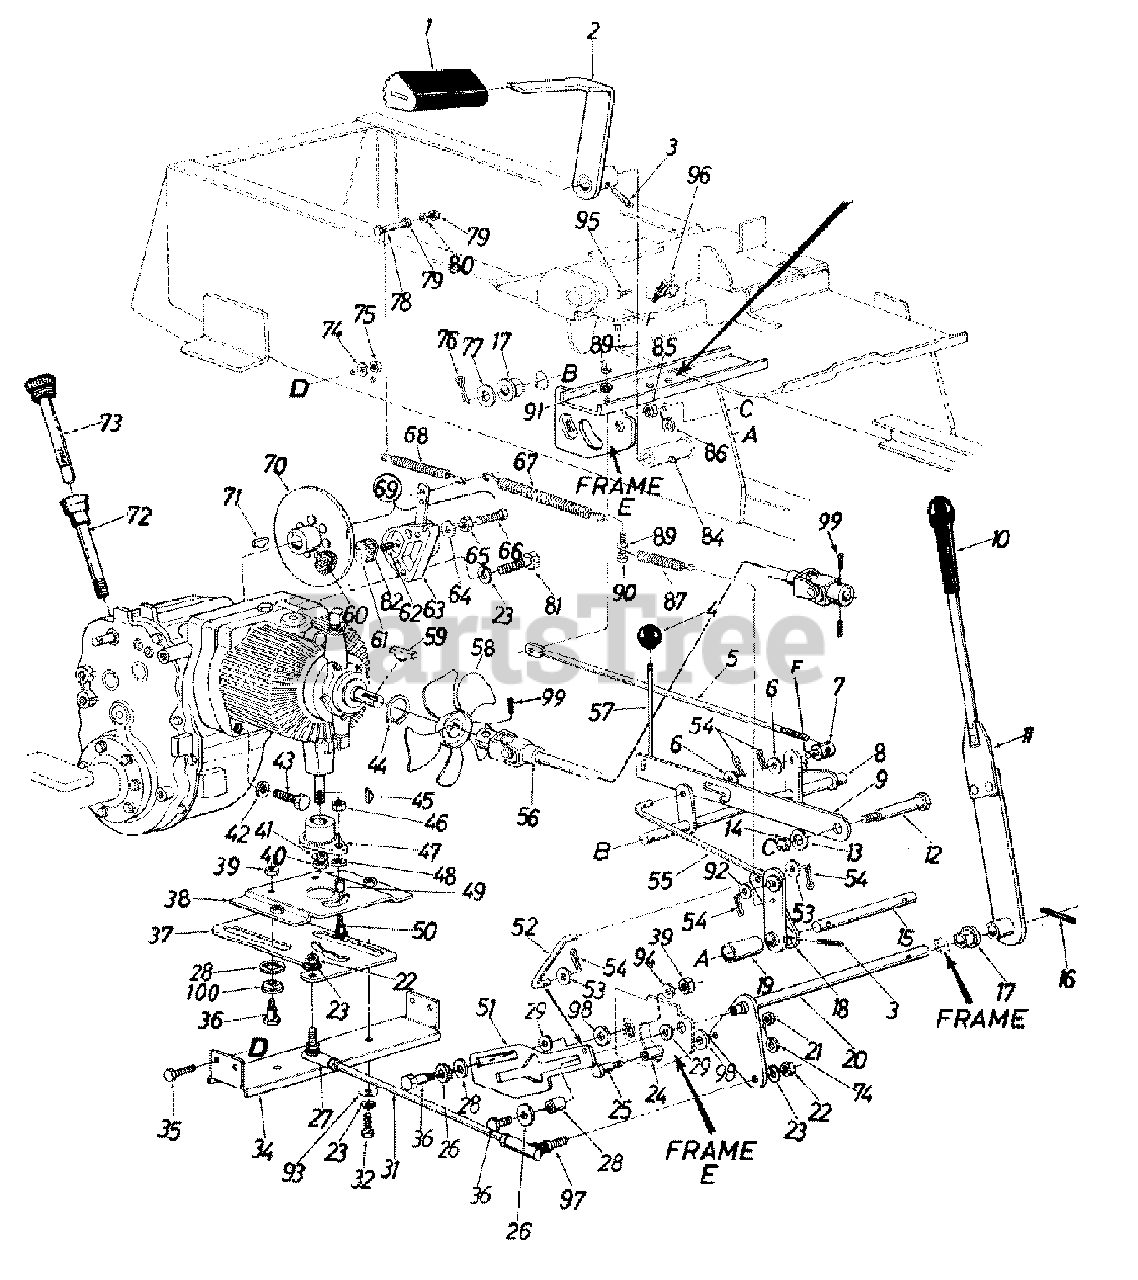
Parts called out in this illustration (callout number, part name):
4	Ball Knob - Brake
6	Fl-Wash. .375" I.D. x 1.00" O.D. x .030"
7	Ferrule
8	Brake Transfer Shaft Ass'y.
9	Parking Brake Cam
11	Control Arm Ass'y. Comp.
12	Shld. Bolt .62" Dia. x 2.75" Lg.
13	Fl-Wash. .460" I.D. x 1.24" O.D. x .06"
14	Push Speed Nut for .625" Dia. Shaft
15	Brake Pivot Shaft
16	Spring Pin Spiral 1/4" Dia. x 1.50" Lg.
17	Hex Flange Brg. Plastic .62" I.D.
18	Brake Lever Ass'y.
20	Control Handle Shaft Ass'y.
21	Hex Cent. L-Nut 5/16-18 Thd.
22	Hex Nut 3/8-24 Thd.
23	L-Wash. 3/8" I.D.
25	Shoulder Bolt
26	Fl-Wash. 7/16" I.D. x 1-3/8" O.D.
27	Ball Joint Ass'y. 3/8-24 Thd. - L.H.
29	Fl-Wash. .325" I.D. x 1.25" O.D.
31	Tie Rod
32	Hex Bolt 3/8-16 x .75" Lg.
34	Support Channel
35	Hex Bolt 5/16-18 x .75" Lg.
36	Shld. Bolt .437" Dia. x .268"
38	Slide Mtg. Plate Ass'y.
39	Hex Cent. L-Nut 5/16-18 Thd.
40	Hex Nut 1/2-13 Thd.
41	L-Wash. 1/2" I.D.
42	Fl-Wash. .385" I.D. x .87" O.D. x .060"
43	Socket Hd. Scr. 3/8-16 x 2.75" Lg.
45	#5 Hi-Pro Key 1/8" x 5/8" Dia.
46	Hex Cent. L-Nut 1/4-20 Thd.
47	Pintle Plate Ass'y.
48	Fl-Wash. .281" I.D. x .50" O.D. x .063"
49	Needle Brg. .31" I.D. x .50" O.D.
50	Shld. Bolt .31" Dia. x .500
51	Neutral Control Slide
52	Neutral Control Rod
53	Fl-Wash. .312" I.D. x .630" O.D.
54	Hairpin Cotter
55	Brake Link Rod Ass'y.
56	Universal Drive Shaft Comp.
57	Parking Brake Link
58	Fan Ass'y.
59	#61 Hi-Pro Key 3/16 x 5/8" Dia.
60	Lining - Brake
61	Lining - Brake
63	Housing with Lever and Pin
64	Washer
65	Nut
66	Adjustment Pin
67	Extension Spring .50" O.D. x 6.5" Lg.
68	Extension Spring (Brake Return)
69	Disc Brake Ass'y. Comp.
70	Brake Disc Ass'y.
71	Hi-Pro Key 3/16 x 3/4" Dia.
72	Dipstick Tube Ass'y.
73	Dipstick Ass'y.
74	L-Wash. 5/16" I.D.
75	Hex Nut 5/16-18 Thd.
76	Cotter Pin 1/8" Dia. x 1.00" Lg.
77	Fl-Wash. .635" I.D. x 1.00" O.D.
78	Hex Scr. 1/4-20 x 2.50" Lg.
79	Hex Nut 1/4-20 Thd.
80	L-Wash. 1/4" I.D.
81	Hex Scr. 3/8-16 x 1.25" Lg.
82	Backing Plate
84	Grease Fitting
85	Hex Nut 7/16-20 Thd.
86	L-Wash. 7/16" I.D.
87	Extension Spring
89	Hex Nut 1/4-20 Thd.
90	Hex Bolt 1/4-20 x 1.25" Lg.
91	L-Wash. 1/4" I.D.
92	Fl-Wash.
93	Fl-Wash. .38" I.D. x 1.25" O.D.
95	Truss Mach. Scr. #10 x .5" Lg.
96	Safety Switch
97	Ball Joint Ass'y. 3/8-24 Thd. - R.H.
98	Fl-Wash. .32" I.D. x .6" O.D.
99	Set Screw 5/16-18 x .38" Lg.
100	Thrust Washer
